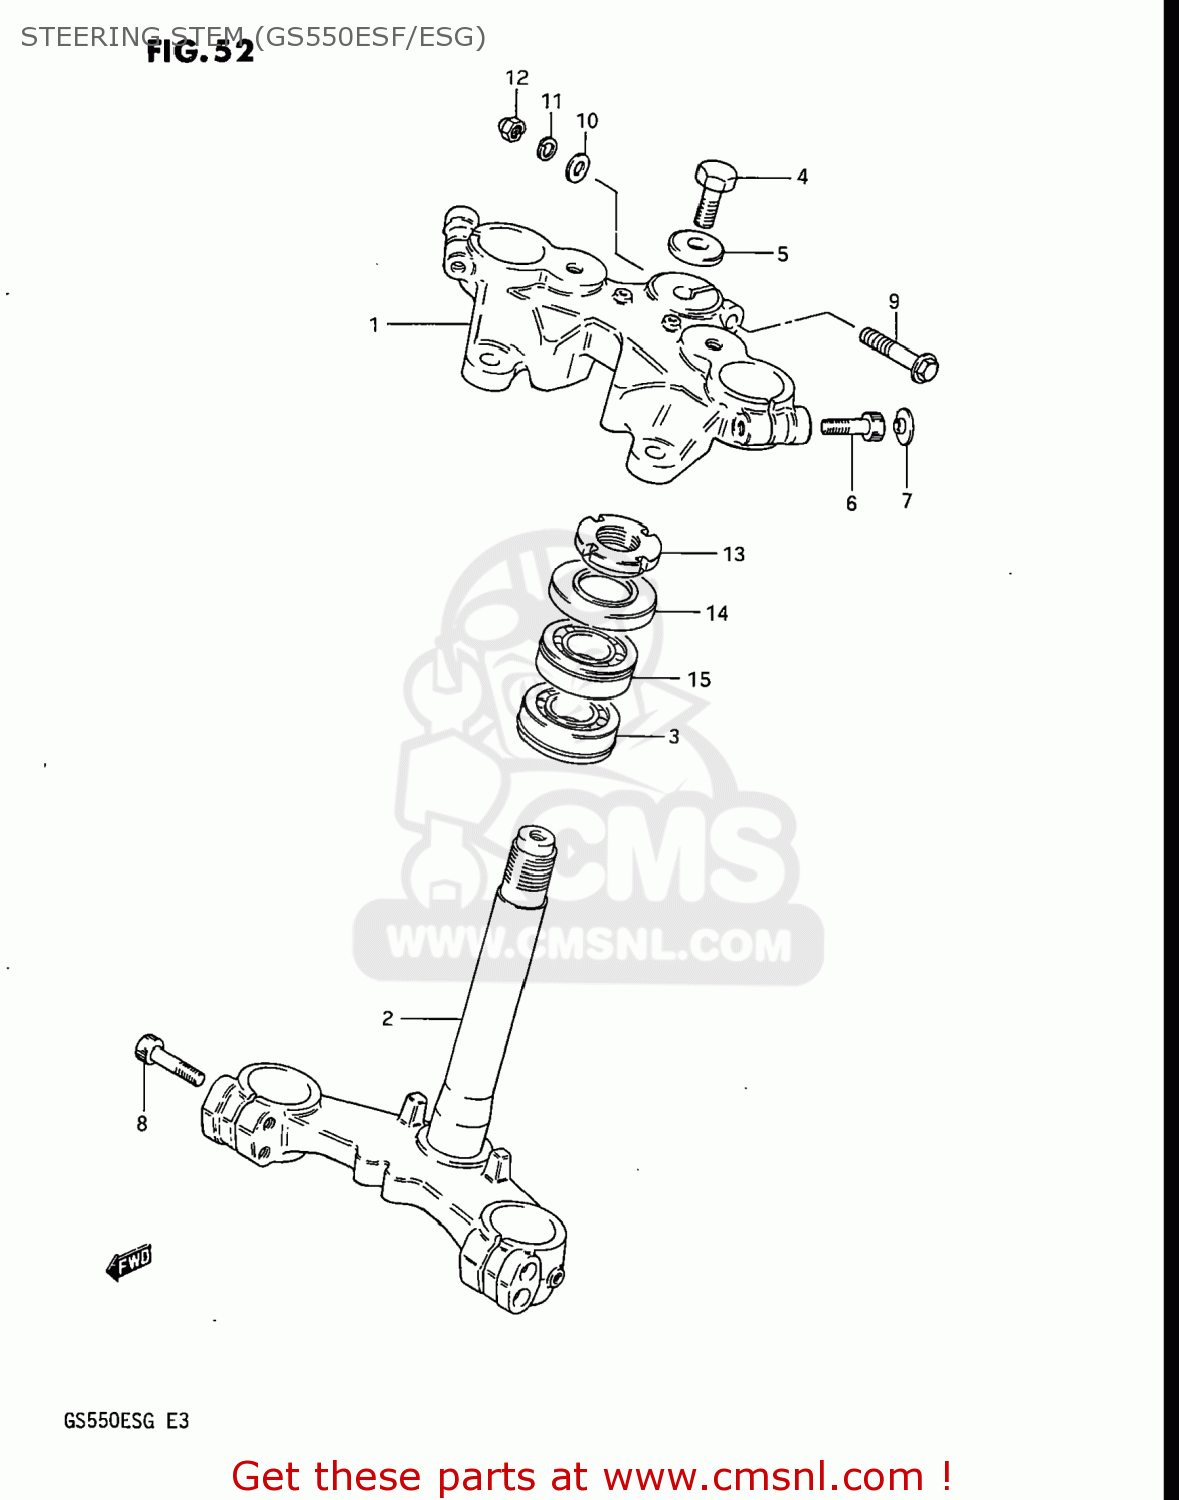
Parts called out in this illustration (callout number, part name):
1	HEAD,STEERING STEM
2	STEM,STEERING
3	BEARING
4	NUT,STEM HEAD
5	SUZUKI
6	BOLT,FORK INNER TUBE FITTING
7	CAP(OD:20)
8	BOLT, REAR (8X30)
9	BOLT, UPPER
10	WASHER
11	WASHER,LOCK,8.
12	NUT,M8X1.25X12
13	NUT,STEERING STEM
14	DUST SEAL,STEERING UPR
15	TAPER,ROLLER BEARING
